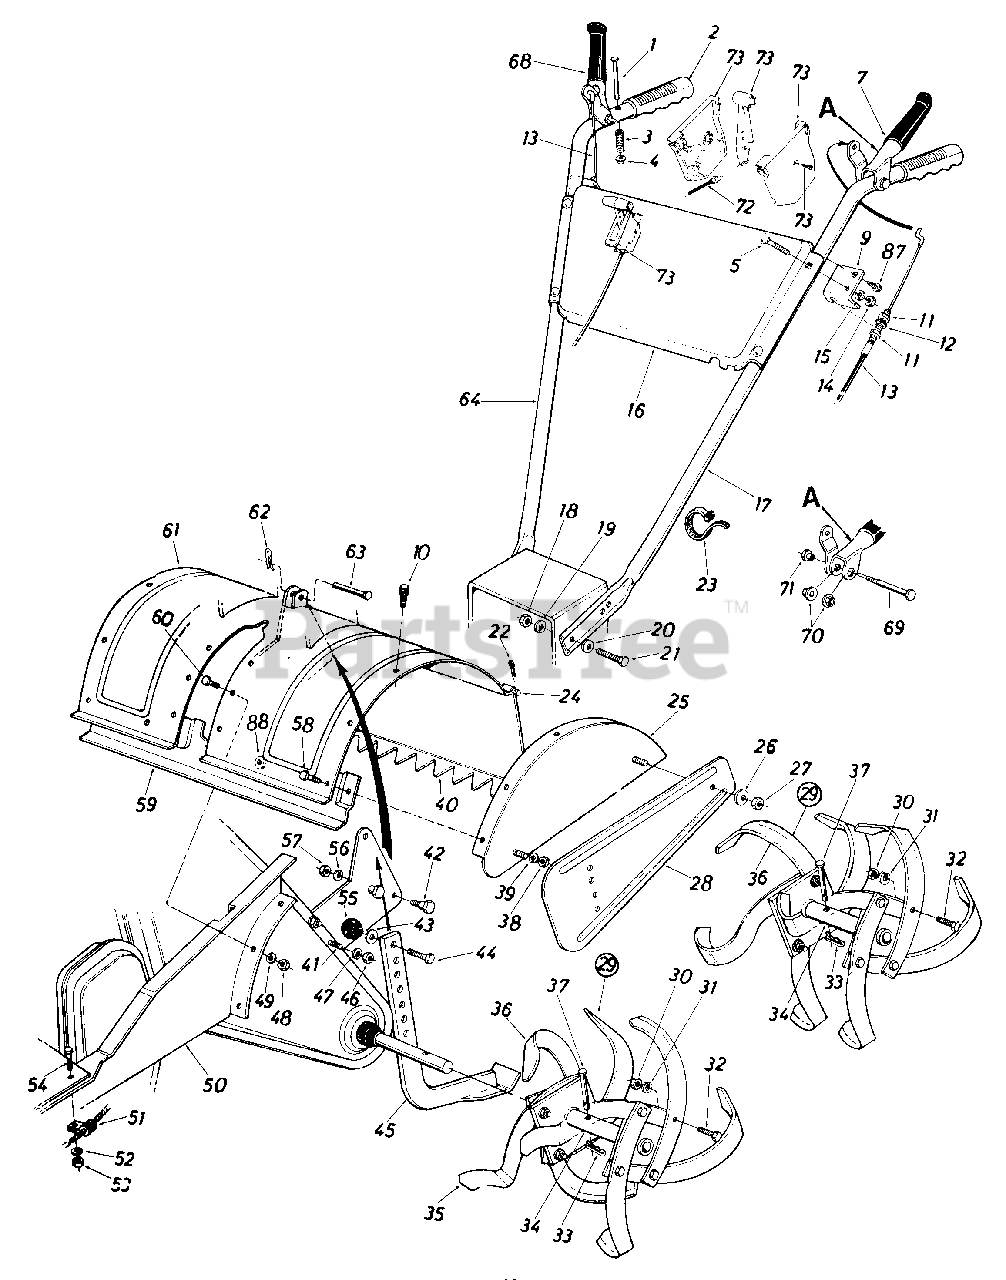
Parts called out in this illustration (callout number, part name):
1	PIN-CLEVIS-1/4 DIA X 2.25 LG
2	GRIP-BLACK
3	SPRING-COMPRESSION
5	BOLT-CARRIAGE 5/16-18 X 1.75
7	GRIP ASSY-CLUTCH-LH
9	BRACKET-CLUTCH
10	SCREW-TAP 5/16-18X.62
11	NUT-HEX JAM 5/16-24
12	WASHER-LOCK-5/16
13	CONTROL-CLUTCH
14	NUT-HEX 5/16-18
15	WASHER-LOCK-5/16
16	PANEL-HANDLE
17	HANDLE-LH
18	NUT-HEX 3/8-16
19	WASHER-LOCK-3/8
20	WASHER-BELL .400 ID X .88 X .060
21	SCREW-HEX 3/8-16 X 1.00
22	PIN-COTTER-3/32 DIA X .75
23	TIE-CABLE
24	ROD-TILLER FLAP
27	NUT-HEX 5/16-18
31	WASHER-LOCK-3/8
32	SCREW 3/8-24X1.25 GR5
33	PIN-COTTER
38	NUT-HEX 5/16-18
39	WASHER-LOCK-5/16
41	BOLT-HEX 5/16-18X1
42	SCREW-SHLD R
43	WASHER-FL-.385 ID X .62 OD X .033
44	SCREW-HEX 3/8-16 X .75
46	NUT-HEX 5/16-18
47	WASHER-LOCK-5/16
48	NUT-HEX 5/16-18
49	WASHER-LOCK-5/16
52	WASHER-LOCK-5/16
53	NUT-HEX 5/16-18
54	SCREW-HEX 5/16-18 X .75
55	KNOB-BALL 1-3/8 " DIA.
56	WASHER-LOCK-3/8
57	NUT-HEX 3/8-16
58	SCREW-HEX 5/16-18 X .75
61	SHIELD ASSY-TINE
62	PIN-COTTER
63	PIN-CLEVIS 3/8 X 1.620
69	SCREW-SHLD .374 DIA X1.530
70	BEARING-FLANGE
71	NUT-SHLD
72	CONTROL-THROTTLE
73	CONTROL-THROTTLE
87	SCREW-HEX WASH SF TAPP
88	WASHER-BELL .337 X .867 X .057
